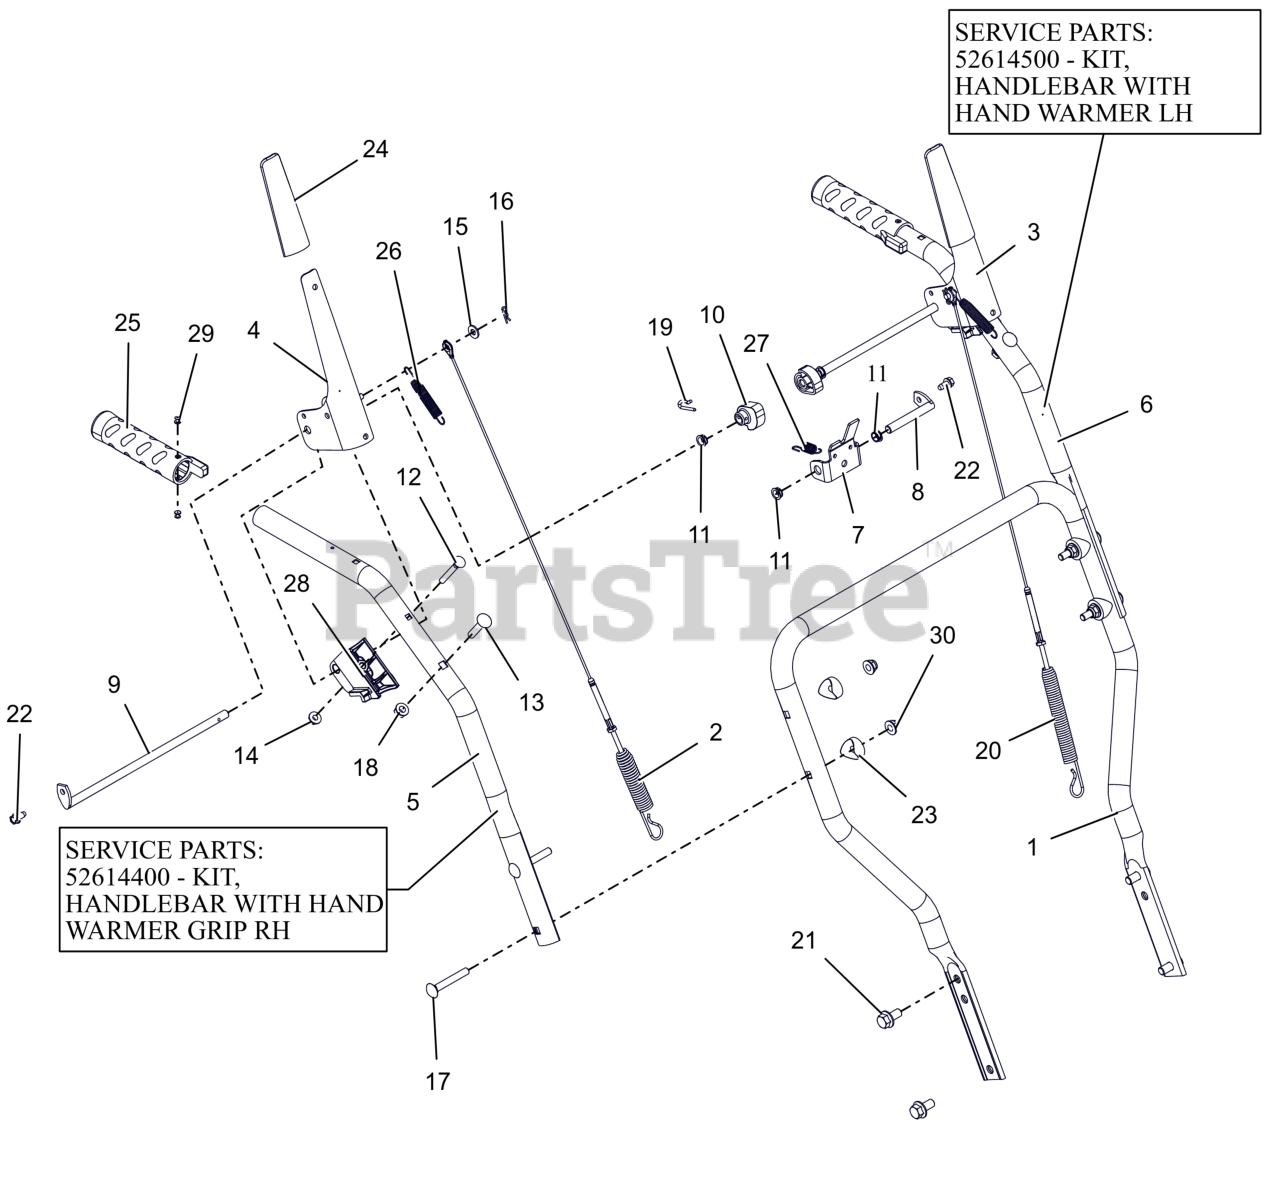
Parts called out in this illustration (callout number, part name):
1	HANDLEBAR, LOWER
2	CABLE, AUGER (DELUXE & PRO)
3	LEVER, CLUTCH-LH
4	LEVER, CLUTCH-RH
5	HANDLEBAR, UPPER - RH
5	KIT, HANDLEBAR HW RH
6	HANDLEBAR, UPPER - LH
6	KIT, HANDLEBAR HW LH
7	BRACKET, INTERLOCK ARM
8	ROD, PIVOT - INTERLOCK
9	ROD, PADDLE MOUNT - PRO
10	CAM, INTERLOCK
11	BUSHING, POLYLINER-.38 SNAPIN
12	BLT-RDHDXLSQNK .25-20X2.0 G5YZ
13	BLT,RHSN .31-18X1.50 G5 ZCC
14	NUT-LK-CTR-FLG .25-20 ZC120
15	WSHR,FLT .281X.625X.065 ZCC
16	PIN, HAIR #178 .06X.77 ZCC
17	BLT, RHSN .31-18X2.25 G5 ZCC
18	NUT-LK-TOP-FLG .312-18 GF ZCC
19	PIN, SPRING CLIP
20	CABLE, UPPER TRACTION
22	SCR-TAP .25-20X.50 HWH ZCC
23	SPACER, HANDLEBAR
24	SLEEVE, CLUTCH PADDLE-GRAY
25	GRIP,HEATED HANDLE-GRAY
26	SPRING, EXTENSION
27	SPRING-EXT .047X.438X1.45
28	BLOCK, CLUTCH PADDLE
29	RVT-POP #43 .125X.313 STL ZINC
30	NUT,LK-NYL-FLG .31-18 G5ZC120
